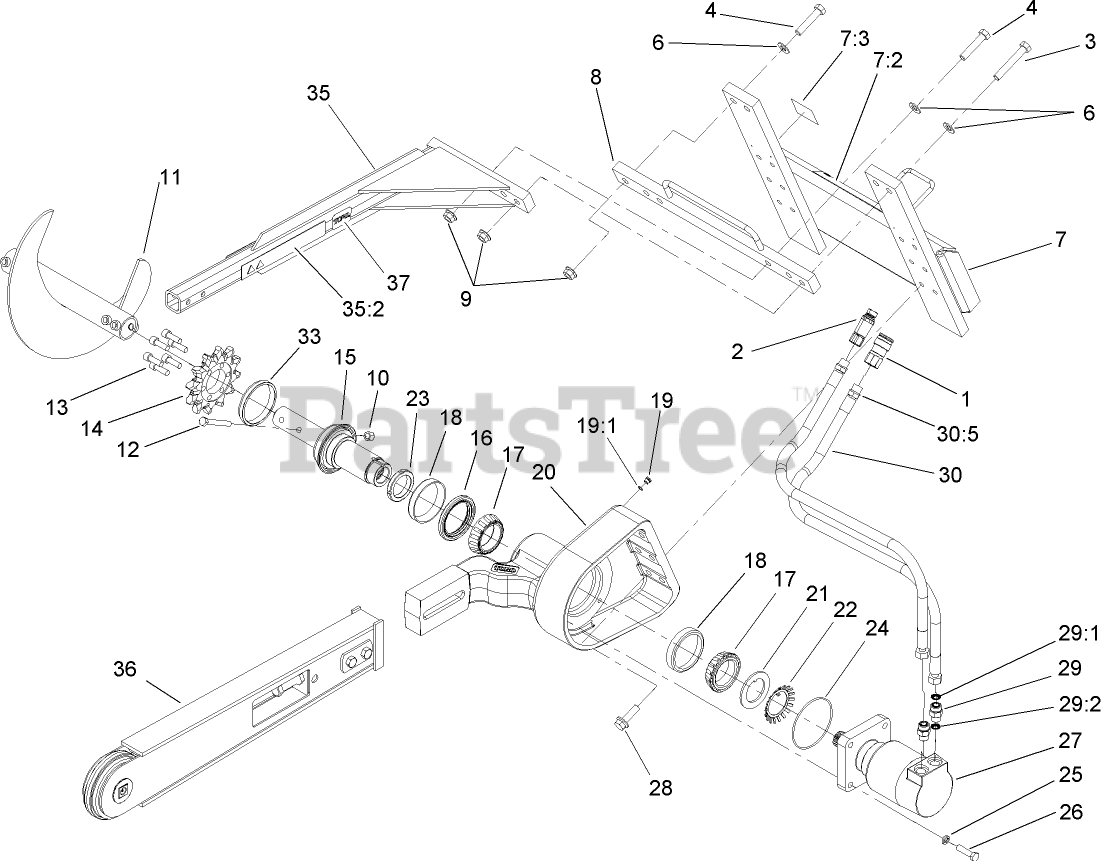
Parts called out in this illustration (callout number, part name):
1	COUPLER-FACE, FLUSH
3	SCREW-HH
4	SCREW-HH
6	WASHER-FLAT
7	MOUNT ASM
7:2	DECAL-DANGER
7:3	DECAL-DANGER
8	CROSSBAR ASM
9	NUT-FLANGE
10	NUT-LOCK, NI
11	AUGER ASM
12	SCREW-HH
13	SCREW-HSH
14	SPROCKET-TRENCHER
15	SHAFT-TRENCHER
16	SEAL-SHAFT
17	CONE-BEARING
18	CUP-BEARING
19	PLUG ASM
19:1	O-RING
20	MOUNT-BOOM
21	WASHER-TONGUED
22	WASHER-LOCK, BEARING
23	NUT-LOCK, BEARING
24	O-RING
25	WASHER-LOCK
26	SCREW-HH
27	MOTOR-HYD, High Speed (only on: 22471)
27	MOTOR-HYD, High Torque (only on: 22470)
29	FITTING-STRAIGHT
29:1	O-RING
29:2	O-RING
30	HOSE ASM
30:5	O-RING
33	SPACER
35	SAFETY RAIL ASM
35:2	DECAL-DANGER
36	BOOM ASM
37	Decal
